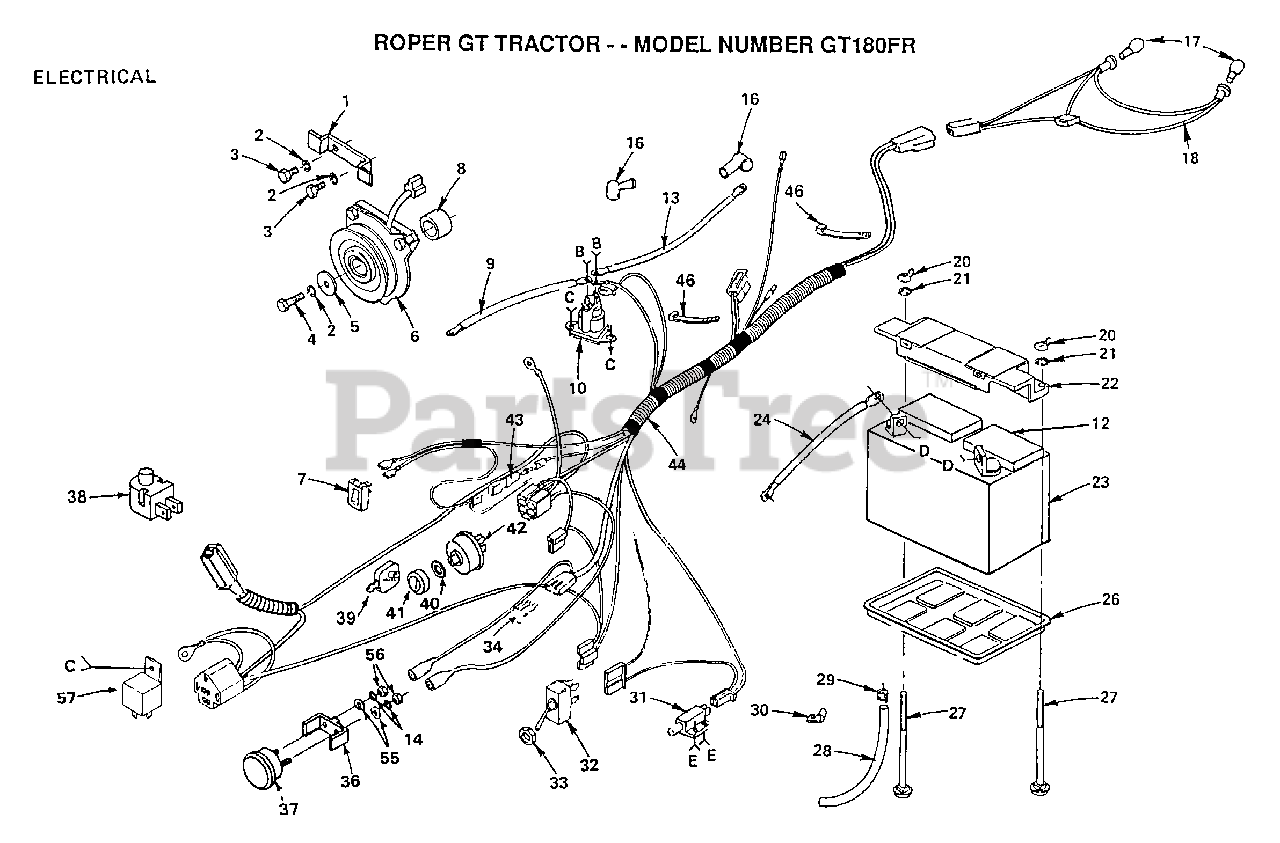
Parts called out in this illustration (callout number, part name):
1	STOP CLUTCH T
2	LOCKWASHER
3	BOLT
4	BOLT
5	WASHER GT
6	CLUTCH.ELECTRIC.T
7	SWITCH LT
8	SPACER-CLUTCH GT
9	CABLE-BATTERY T
12	"CAP,BATTERY "
18	HARNESS T
21	LOCKWASHER GT
24	CABLE T
26	"TRAY T, BATTERY"
27	BOLT
29	HOSE CLAMP T
30	CLIP GTV
31	SWITCH-INTER. GT
32	SWITCH.PTO.T
33	HEX NUT T
34	FUSE-30 AMP
37	AMMETER T
38	SWITCH SEAT
44	HARNESS IGNITIO
46	WIRE TIE
55	WASHER
57	RELAY ASSY T
